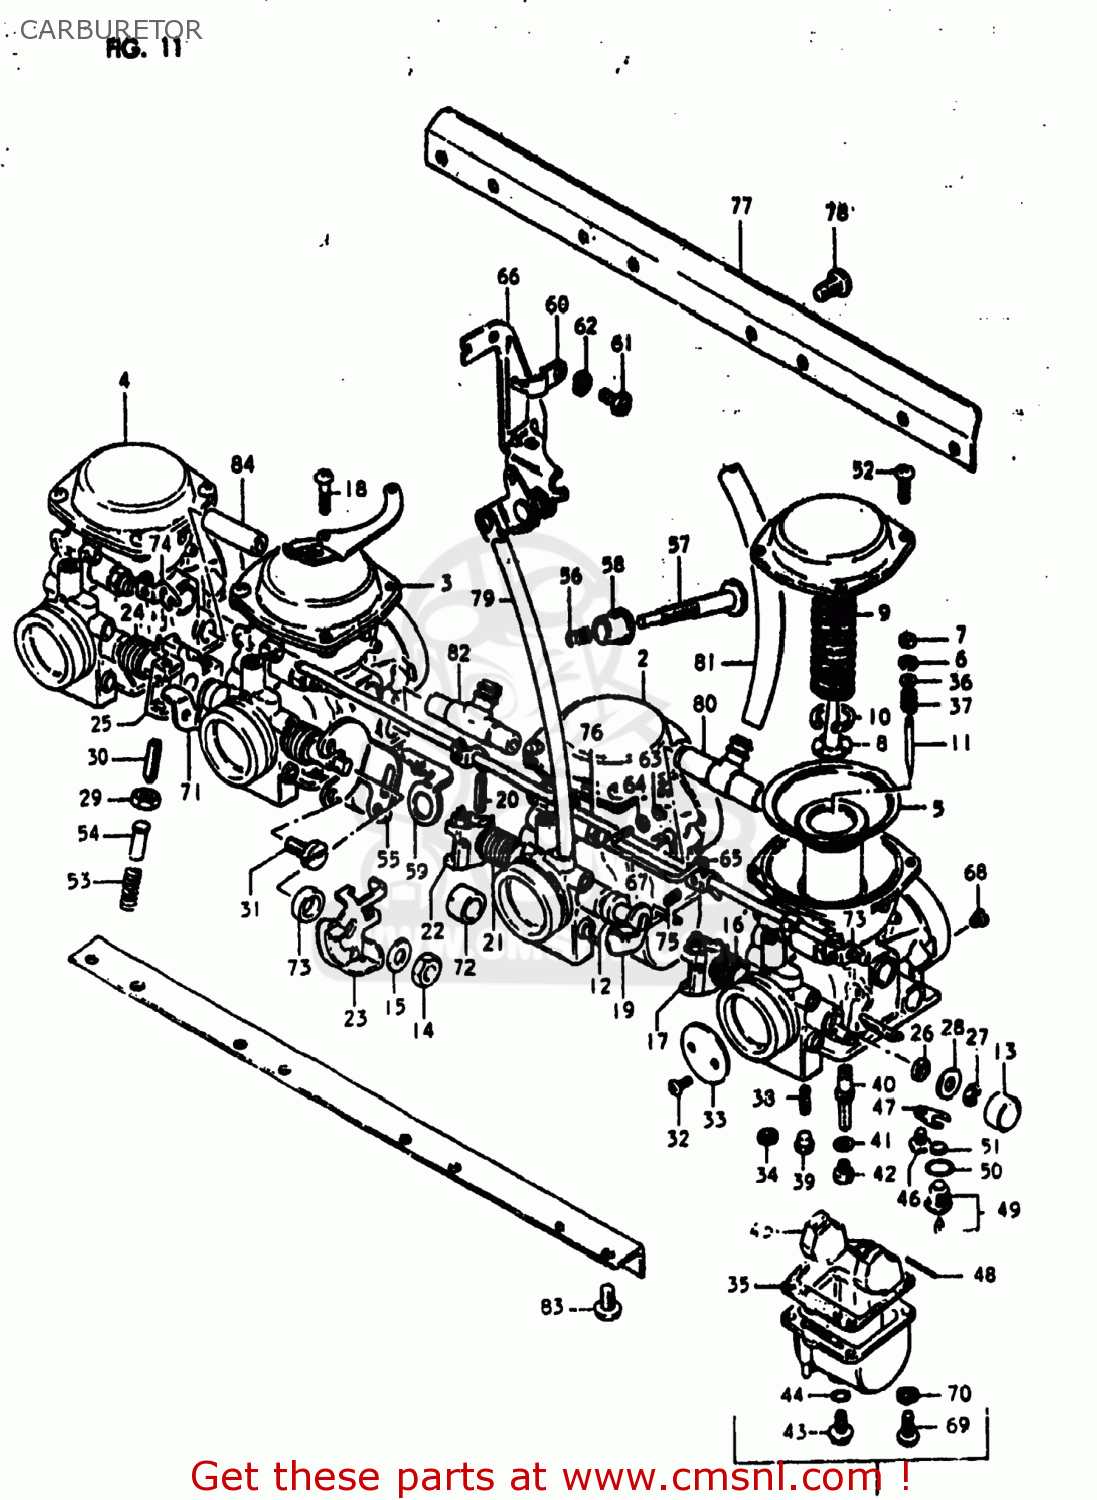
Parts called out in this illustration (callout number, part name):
1	CARBURETOR ASSEMBLY
2	CARBURETOR ASSEMBLY
3	CARBURETOR ASSEMBLY
4	CARBURETOR ASSEMBLY
5	DIAPHRAGM ASSEMBLY
6	CLIP,NEEDLE
7	RING
8	HOLDER,GUIDE
9	SPRING
10	E RING
11	NEEDLE JET
12	GASKET
13	CAP
14	NUT
15	WASHER
16	SPRING,THROTTLE SHAFT
17	SHAFT,THROTTLE
18	SCREW
19	SHAFT,THROTTLE
20	PIN,THROTTLE SHAFT
21	SPRING,THROTTLE SHAFT
22	LEVER,THROTTLE SHAFT
23	LEVER ASSEMBLY,THROTTLE
24	SPRING,THROTTLE SHAFT
25	SHAFT,THROTTLE
26	SEAL
27	E RING
28	GASKET,THROTTLE SHAFT (NAS)
29	NUT
30	SCREW
31	SCREW
32	SCREW
33	VALVE,THROTTLE (BUTTERFLY)
34	GASKET (NAS)
35	GASKET,FLOAT CHAMBER (NAS)
36	WASHER
37	SPRING
38	JET,PILOT
39	PLUG,NEEDLE JET
40	JET,NEEDLE
41	WASHER,NEEDLE NOZZLE
42	JET,MAIN(107.5)
43	PLUG,DRAIN
44	GASKET (NAS)
45	FLOAT
46	SCREW
47	PLATE
48	PIN,FLOAT
49	VALVE ASSEMBLY,NEEDLE
50	O RING
51	FILTER
52	SCREW
53	SPRING,THROTTLE SCREW
54	PIN,THROTTLE LEVER
55	BRACKET,THROTTLE ADJUST
56	SPRING
57	SCREW
58	BUSH
59	BRACKET,THROTTLE ADJUST
60	BRACKET,STARTER
61	BOLT
62	LOCK WASHER
63	CAP,LEVER
64	SEAT,SPRING
65	LEVER ASSY
66	BRACKET
67	ROD,STARTER LEVER
74	LEVER
75	SCREW
76	SHAFT,STARTER
77	BRACKET
78	SCREW
79	HOSE
80	NIPPLE
81	HOSE
82	NIPPLE
83	SCREW 6X12
84	NIPPLE
